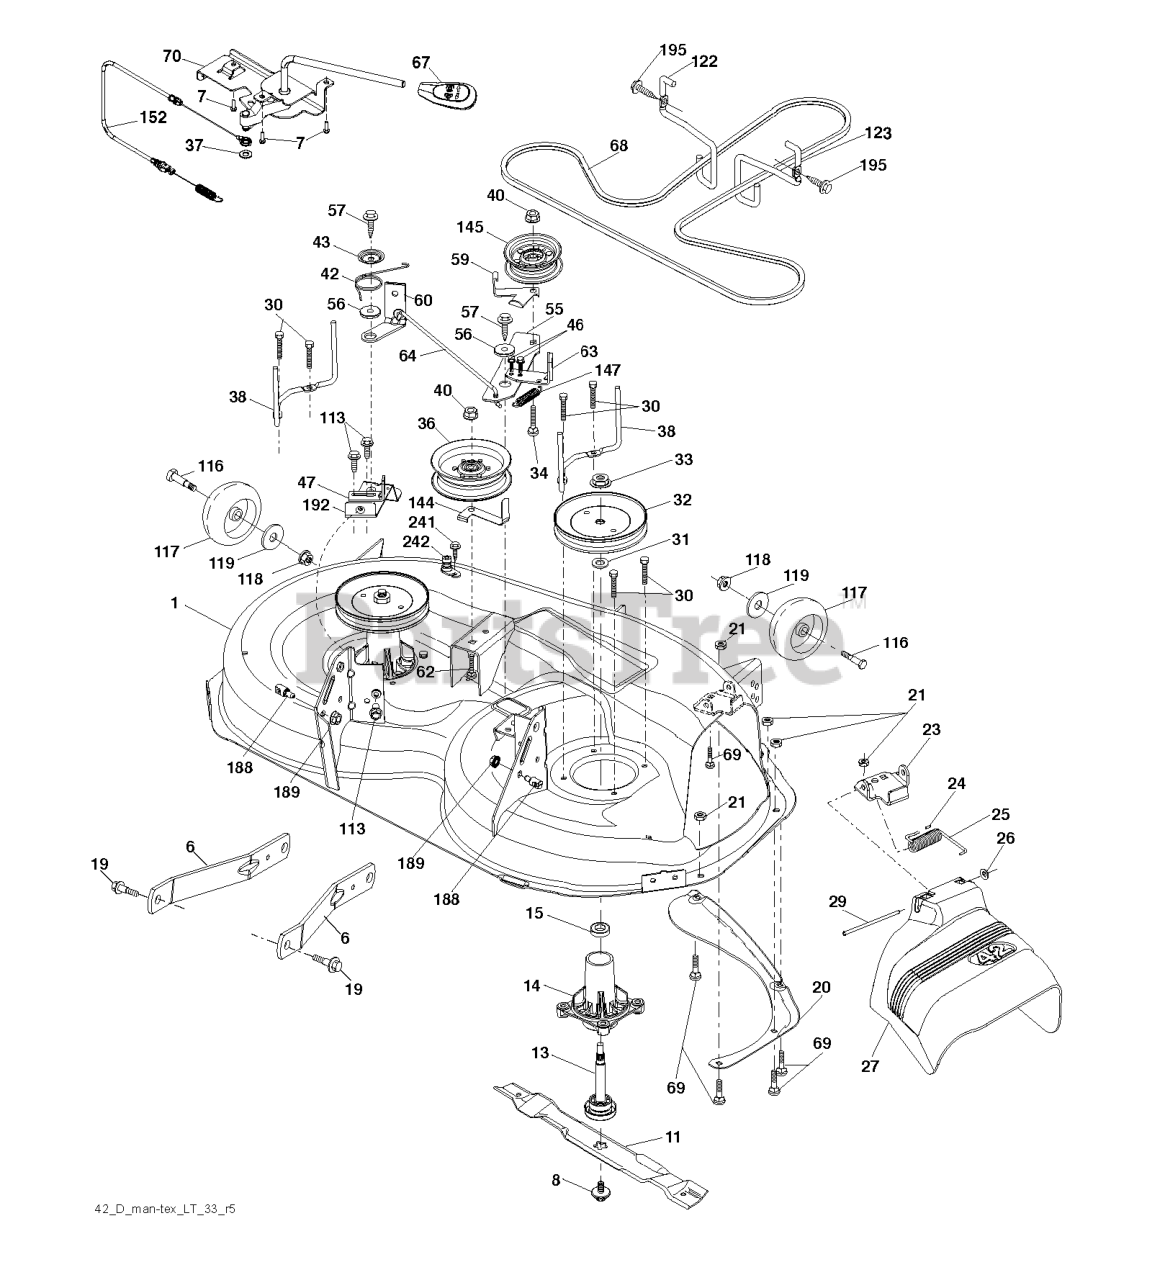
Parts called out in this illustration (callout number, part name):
1	DECK.WELDMENT.42"
6	ARM.SUSPENSION.MOWER.R
7	SCREW.#10 X 0.750.BOS
8	BOLT.WASHER.ASM.7/16-2
11	42" HI-LIFT BLADE
13	SHAFT.ASM.MDRL.N/GREASE.38
14	RP.HOUSING.MANDREL.4PT.
19	BOLT.SHOULDER
20	BAFFLE.VORTEX
21	LOCKNUT
23	BRKT.DEFLECTOR.38"2005+
24	CAP-SLEEVE LT
25	SPRING.TORSION.DEFLECT
26	NUT PUSH M
27	SHIELD.DEFLECTOR.MOWER.42"BLAC
29	ROD.HINGE
30	SCREW, WASHER HEAD
31	WASHER.SPACER.MANDREL
32	PULLEY.MANDREL.5.438.PD
33	NUT.FLANGE.LOCK.TOP
34	BOLT.3/8-16X1.50
36	PULLEY.IDLER.2006
37	WASHER
38	KEEPER.BELT.LH.MANDREL
40	NUT LOCK FLG 3/8-16 UNC
42	SPRING.TORSION.BRAKE
43	SRPING.TORSION.RETAINE
46	SCREW.1/4-20X5/8
47	BRKT.CLUTCH.CABLE
55	IDLER.ARM.42"
56	SPACER.RETAINER
57	SCREW 3/8-16X1
59	GUARD, BELT
60	ARM BRAKE MOWER
63	ARM BRAKE MOWER
64	LINK BRAKE
67	HANDLE.CLUTCH.CABLE.LT
68	BELT.DECK.DRIVE.42"
69	BOLT
70	CLUTCH.ASM.MANUAL.LT.PRED
113	BOLT.5/16HEX.WHS.HD
116	BOLT M
117	WHEEL.GAGE.HALF.SPOKED
118	NUT LOCK FLG 3/8-16 UNC
119	WASHER.5/16.FLAT.STE.STD.
122	KEEPER BELT ENGINE LH
123	KEEPER BELT RH
144	KEEPER.BELT.MOWER
145	PULLEY.IDLER.48"PRIMARY
147	RETURN SPRING
152	CLUTCH CABLE
188	STUD.FASTNER.W/ANTI-ROTATE
189	NUT LOCK HEX FLANGE 5/16-18
192	BRKT.BRAKE.STAND.LH.
195	SCREW, 3/8-16X3/4
241	SCREW.TT.#10-32X.5.3/8.FLANGE
242	PORT.WASHOUT
